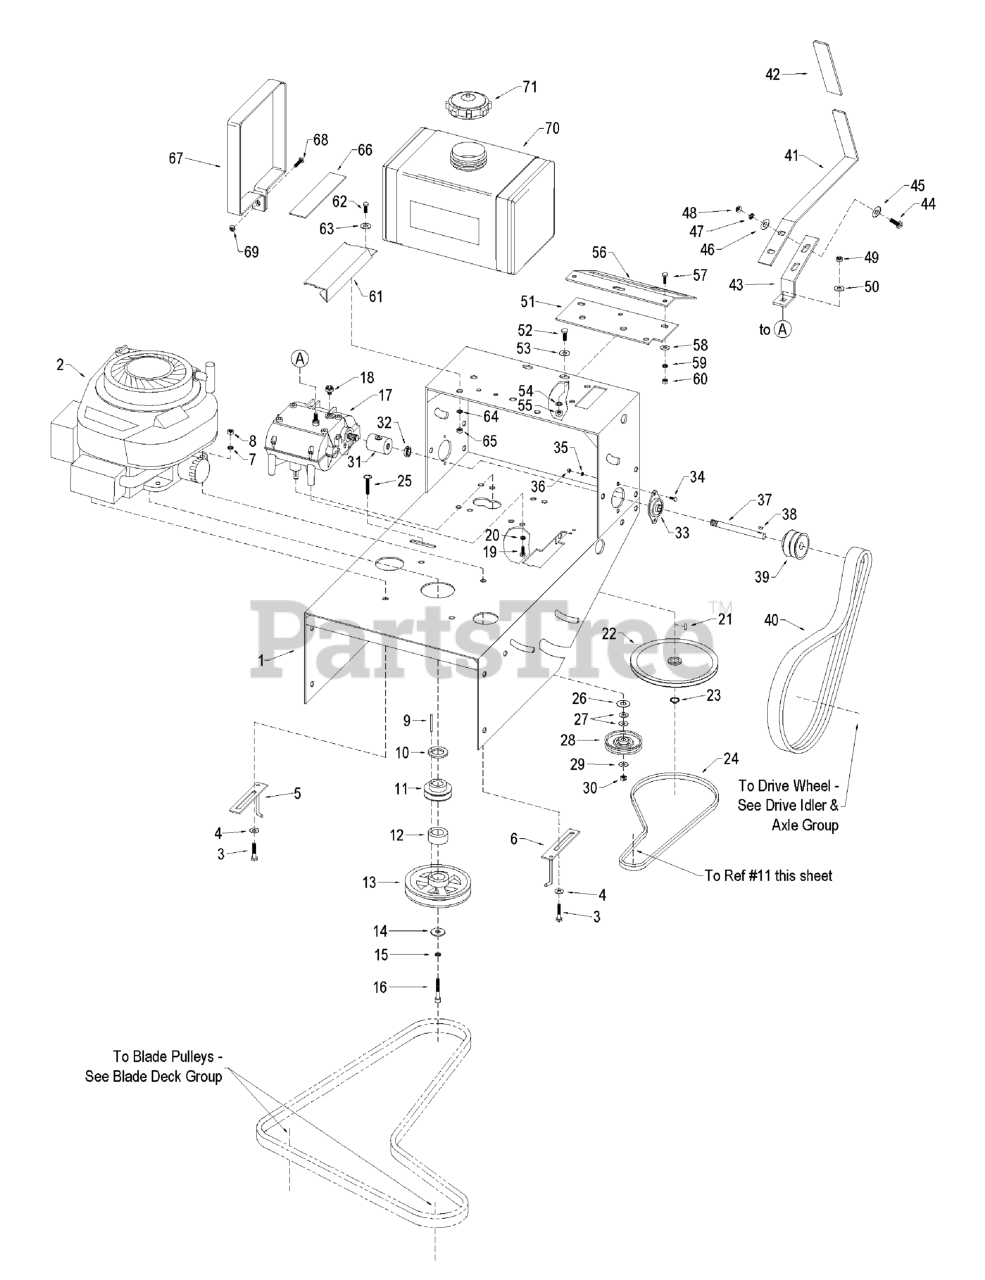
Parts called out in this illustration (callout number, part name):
1	Engine deck
2	ENGINE, 13.5HP Briggs & Stratton Intek
2	ENGINE, 12.5HP Kawasaki
3	BOLT, 5/16-18 x 1-1/2
3	BOLT, M8-1.25 X 25MM GR 8.8
4	WASHER, 5/16" SAE
5	Belt guide - engine right front
6	Belt guide - engine left rear
7	WASHER, 5/16 LOCK CZ
8	NUT, 5/16-18 HEX
9	KEY, 1/4 SQ. X 2-3/4
10	1/4" spacer
11	Engine-to-trans pulley
12	3/4" spacer
13	Blade drive pulley
14	7/16" heavy duty washer
15	WASHER, 7/16" Lock
16	BOLT, Socket Head, 7/16-20 x 2
16	BOLT, M10 x 30MM
17	5 SPEED GEARBOX
18	SWITCH, NEUTRAL SAFETY
19	BOLT, 5/16-18 X 3/4 GD5
20	WASHER, 5/16 LOCK CZ
21	KEY, #9 Woodruff
22	Transmission pulley
23	5/8" snap ring
24	Transmission belt
25	Trans idler bolt
26	WASHER, 3/8 SAE
27	WASHER, 5/16" SAE
28	Trans idler pulley
29	WASHER, 5/16" SAE
30	NUT, 3/8-16 HEX NYLON LOCK
31	COUPLER
32	COLLAR, 5/8" Split
33	FLANGE BEARING
34	HHCS, 1/4-20 X 0.625, GR5, ZINC/CLEAR
35	WASHER, 1/4 LOCK
36	NUT, 1/4-20 Hex
38	KEY, #9 Hi Pro Woodruff
39	PULLEY, Double-A Section
40	BELT, Double-A Section
41	GEAR SELECTOR HANDLE
42	GRIP, FOAM, 1/4 X 1 X 4.1
43	LEVER, Gear Selector
44	BOLT, 5/16-18 x 1-1/4
45	WASHER, 5/16" SAE
46	WASHER, 5/16" SAE
47	WASHER, 5/16 LOCK CZ
48	NUT, 5/16-18 HEX
49	NUT, 3/8-16 HEX NYLON LOCK
50	WASHER, 3/8 SAE
51	Shift indicator mounting plate
52	BOLT, 5/16-18 X 3/4 GD5
53	WASHER, 5/16" SAE
54	WASHER, 5/16 LOCK CZ
55	NUT, 5/16-18 HEX
56	GUIDE, Gear Selector
57	BOLT, 1/4-20 x 3/4
58	WASHER, 1/4 SAE
59	WASHER, 1/4 LOCK
60	NUT, 1/4-20 Hex
61	Fuel tank mount - right
62	BOLT, 5/16-18 X 3/4 GD5
63	WASHER, 5/16" SAE
64	WASHER, 5/16 LOCK CZ
65	NUT, 5/16-18 HEX
66	RUBBER PAD
67	FUEL TANK STRAP
68	BOLT, 1/4-20 X 1-1/2
69	NUT, 1/4-20 HEX NYLON LOCK
70	TANK, FUEL, PLASTIC, 5 GALLON W/ FUEL LINE
71	CAP, GASOLINE, VENTED
